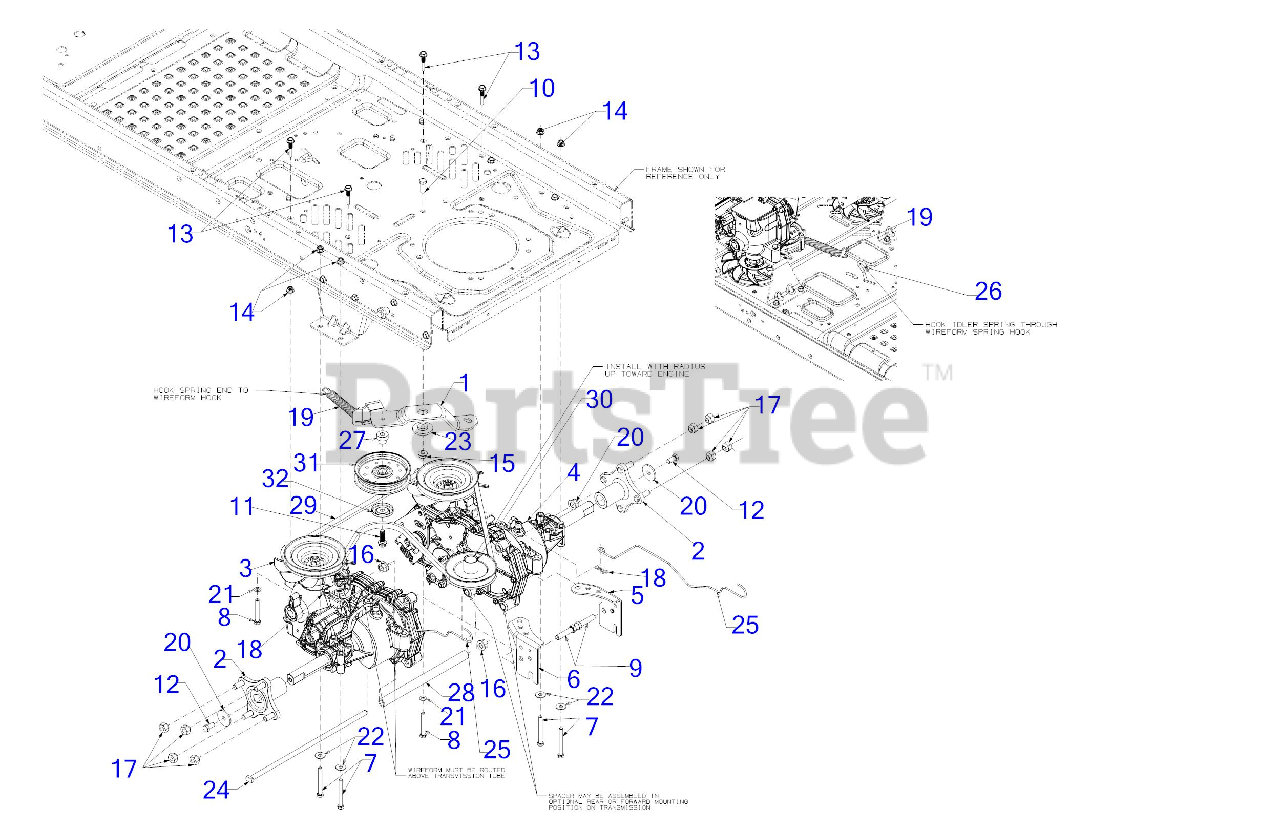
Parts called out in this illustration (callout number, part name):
1	IDLER BRACKET ASSEMBLY
2	WHEEL HUB ASSEMBLY
3	HYDRO TRANSMISSION ASSEMBLY (LH)
4	HYDRO TRANSMISSION ASSEMBLY (RH)
5	TRANSMISSION MOUNTING BRACKET (RH)
6	TRANSMISSION MOUNTING BRACKET (LH)
7	HEX SCREW 5/16-18 x 2.75
8	HEX SCREW 5/16-18 x 2.25 GR5
9	SCREW 7/16-20 x 1.75 GR 5
10	SCREW 3/8-16 x 1 GR5
11	SCREW 3/8-16 X1.250
12	SCREW 3/8-16 x .75 GR 5
13	BELT KEEPER ROD .25 x 1.585
14	FLANGE LOCK NUT 5/16-18
16	FLANGE LOCK NUT
17	LUG NUT 7/16-14
18	BOW TIE COTTER PIN 1/4-5/16
19	EXTENSION SPRING .75 DIA x 5.87
20	FLAT WASHER .390x1.500x.134
21	FLAT WASHER
22	FLAT WASHER
23	SHOULDER SPACER
24	SUPPORT TUBE ROD
25	HYDRO BYPASS ROD
26	IDLER SPRING HOOK
27	SHOULDER SPACER
28	SUPPORT TUBE
29	TRANSMISSION DRIVE BELT A x 67
30	TRANSMISSION DRIVE PULLEY
31	IDLER PULLEY 4.25 DIA
32	IDLER PULLEY CAP
